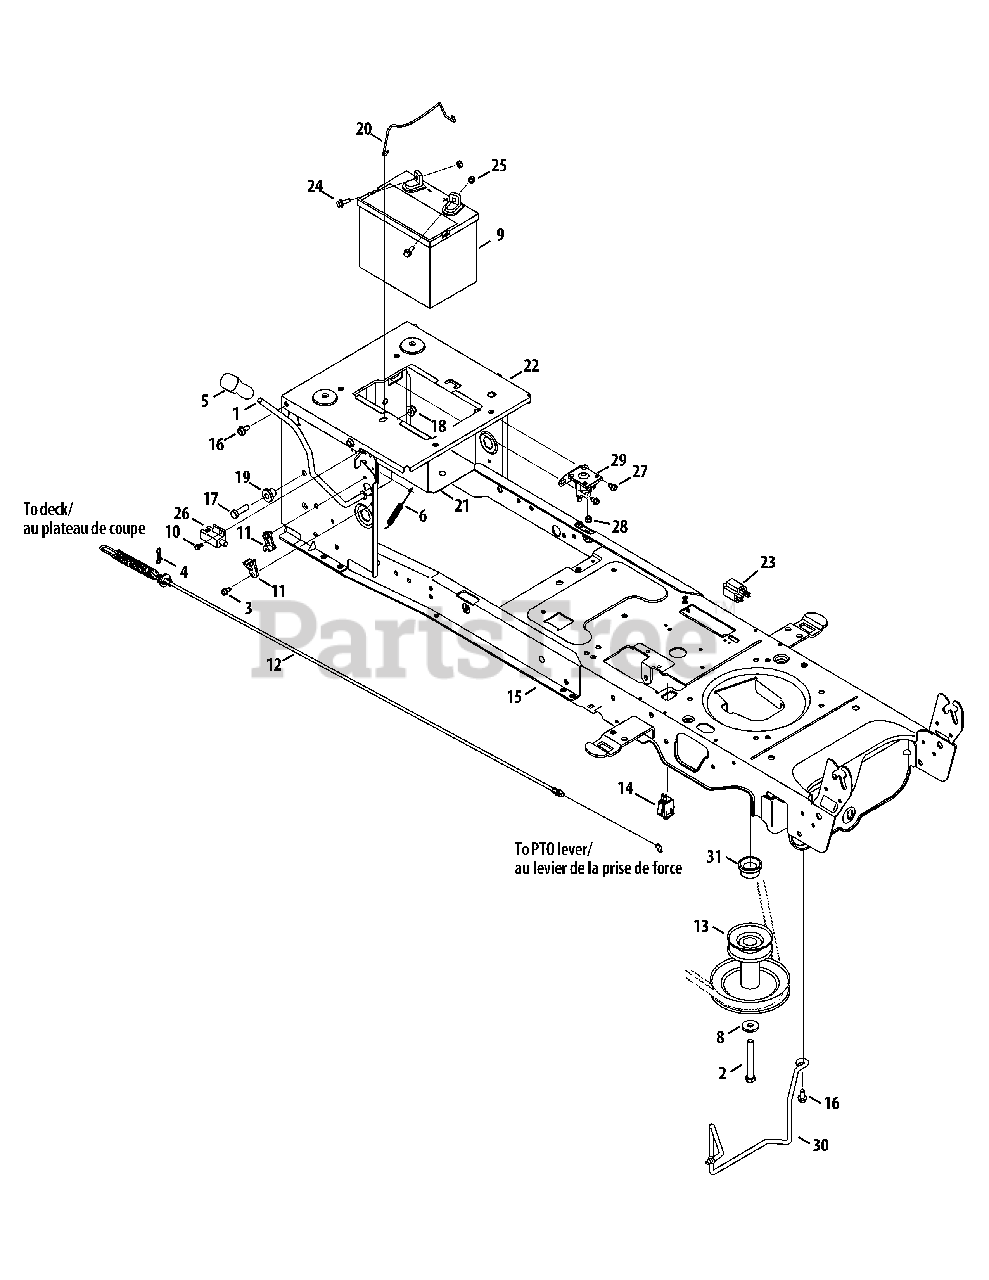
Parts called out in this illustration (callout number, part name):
1	Handle Ass’y , PTO
2	Hex Screw 7/16-20 x 3.5 Gr. 5
3	Hex Wash S-Tapp Scr 1/4-20 x .50
4	Bow-Tie Cotter Pin
5	Handle Grip 3/8
6	Extension Spring .38 Dia. x 5.6
7	Lockwasher 7/16 ID
8	Flat Washer .450 x 1.25 x .164
9	Battery 245 CCA (Dry)
10	Shoulder Screw #10-32 x .50
11	Bearing, PTO
12	Deck Engagement Cable
13	Engine Pulley 3.56 x 6.12 Dia. (Hydrostatic Models)
14	Switch, Plunger, snap mount
15	Lower Frame Ass’y
16	Hex Wash Hd. Tapp Scr. 5/16-18 x .75
17	Hex Bolt 3/8-16 x 1.25
18	Flange Lock-Nut 3/8-16 Gr. F Ny lon
19	Shoulder Spacer .38 x 1.0 x .70
20	Battery Retainer Rod
21	Battery Tray
22	Seat Frame Bracket
23	Switch, 3-Pole, (NC-NO-NO)-Brake
24	Hex Hd. Flg. Scr. 1/4-20 x .75 Gr. 5
25	Sems Hex Nut 1/4-20
26	Switch, In ter lock
27	Hex Wash HD Tapp Scr 1/4-20 x .375
28	Hex L-Flanged Nut 1/4-20 Gr. F Ny lon
29	Solenoid
30	Belt Keeper Rod
